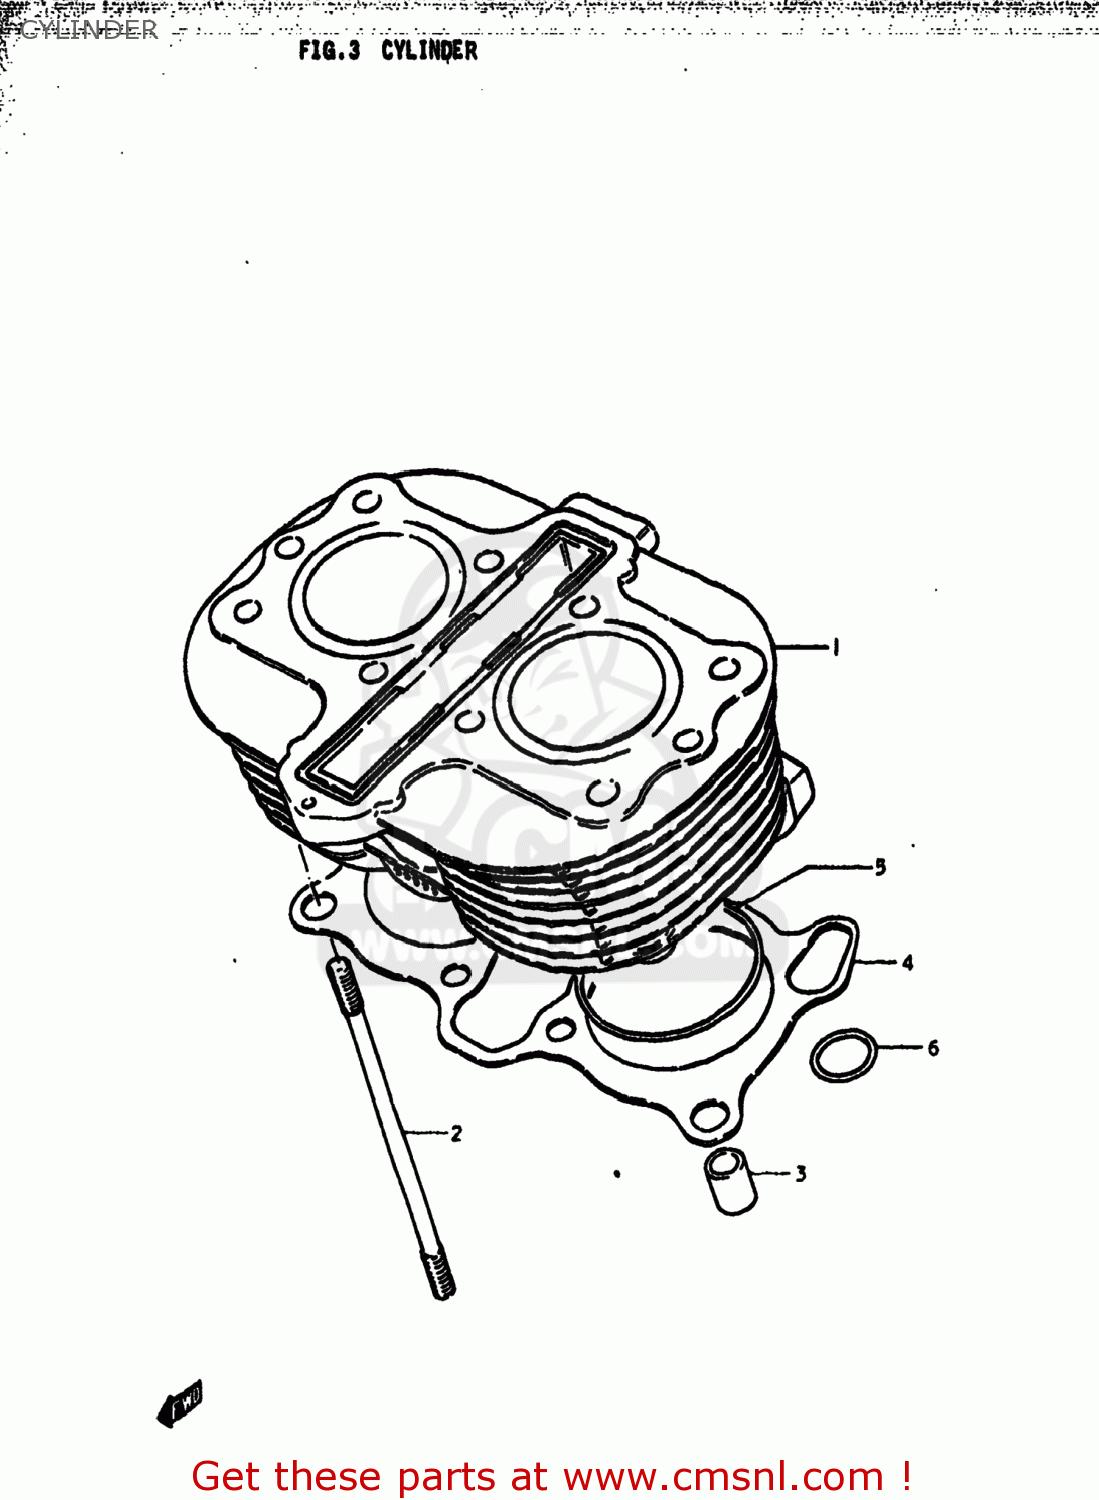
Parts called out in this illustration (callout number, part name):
1	CYLINDER
2	STUD
3	PIN
4	GASKET,CYLINDER (MCA)
5	O RING(D:2,ID:70)
6	O RING(D:3.05)
